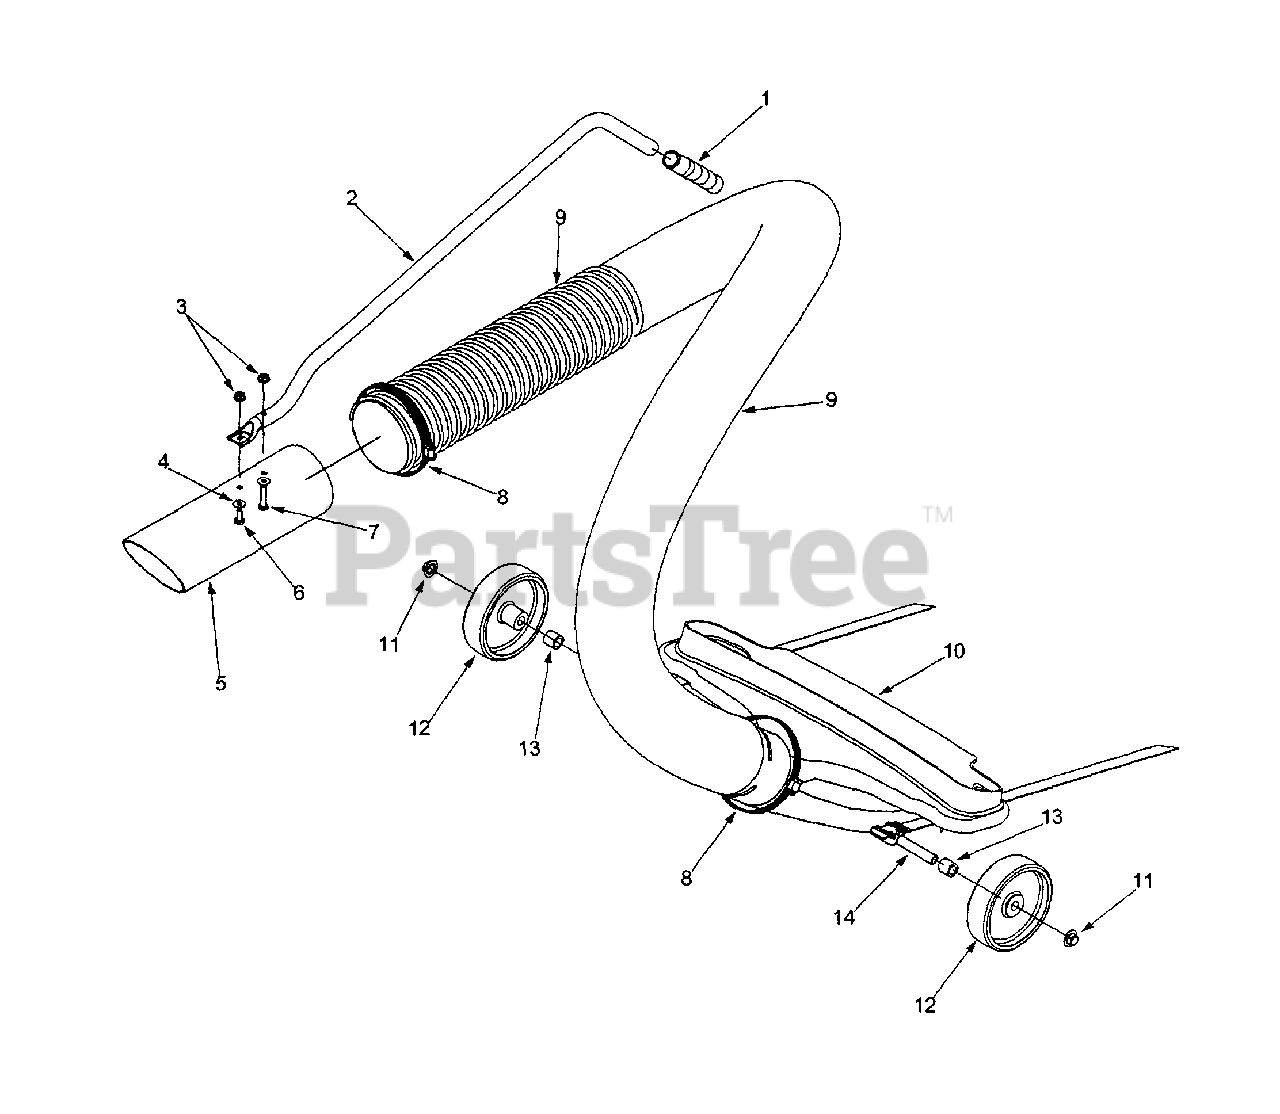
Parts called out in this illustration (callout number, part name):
1	Handle Grip
3	Hex Lock Nut 1/4-20
4	Flat Washer.271 ID x .630 OD
5	Nozzle 3.875 x 12.0
6	Hex Cap Screw 1/4-20 x .620
7	Hex Cap Screw 1/4-20 x 1.25
8	Adjustable Clamp
9	Vacuum Hose
10	Hose Attachment Nozzle Ass'y
12	Wheel 5.0 x 1.38
14	Axle.50 OD x .354 ID x 16.7
